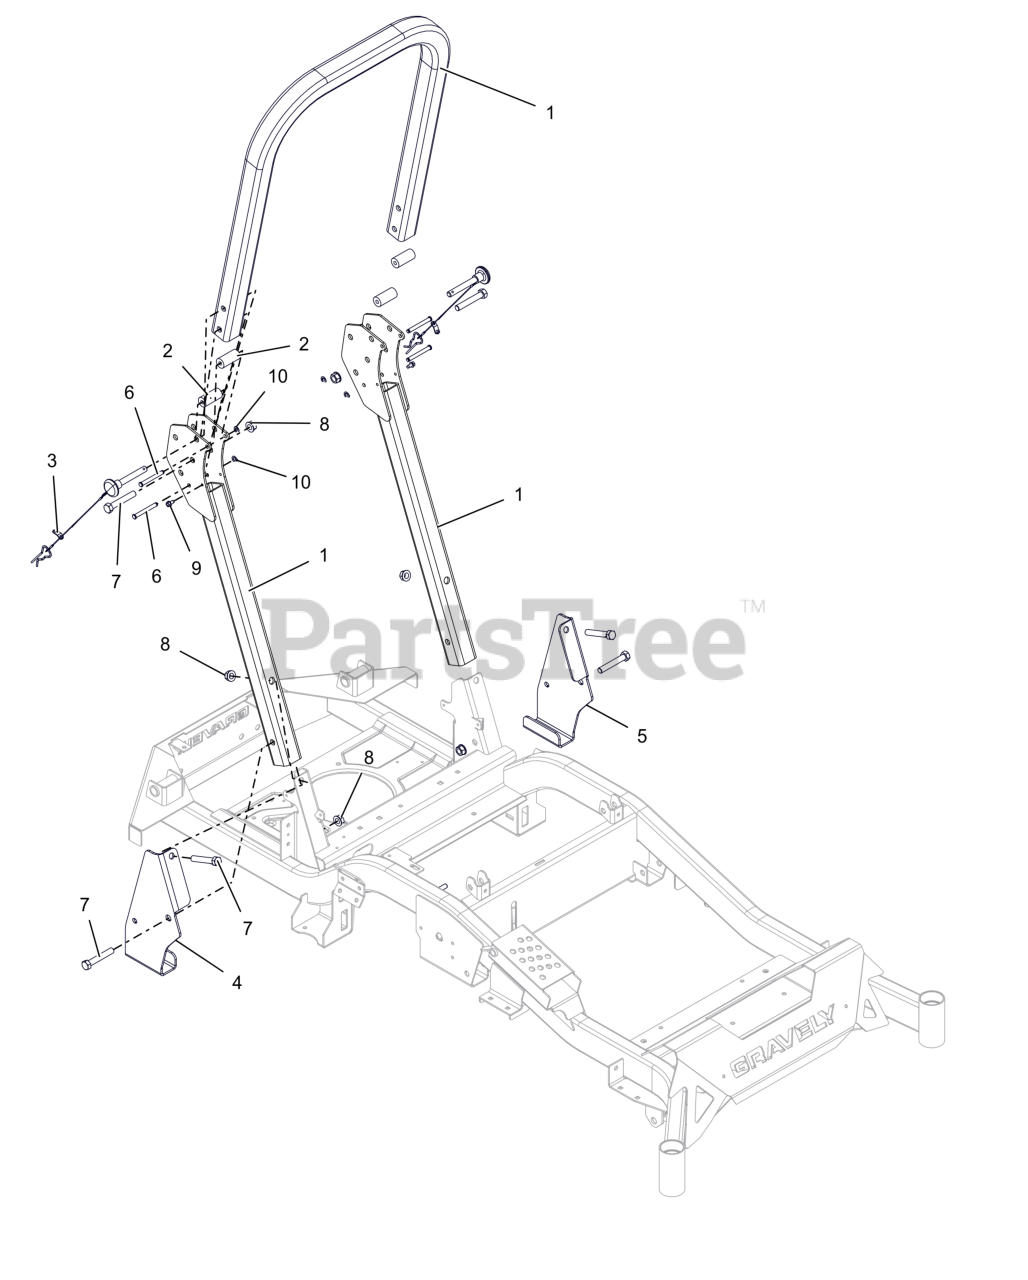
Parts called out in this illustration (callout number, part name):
1	ROPS,PROTURN Z REPLACEMENT-TALL
2	BUMPER, ROPS ANTI-VIBRATION
3	PIN, ROPS W/LANYARD
4	BRKT, ROPS SUPPORT - RH
5	BRKT, ROPS SUPPORT -LH
6	PIN, 5/16 X 2-9/16 WITH GROOVE
7	BLT, HEX .50-13X3.00 G5 ZCC
8	NUT-LK-CTR-FLG .500-13 GG ZCC
9	SCR-TAP .25-20X.50 HWH ZCC
10	RING, RETAINING-E .312 X .025
